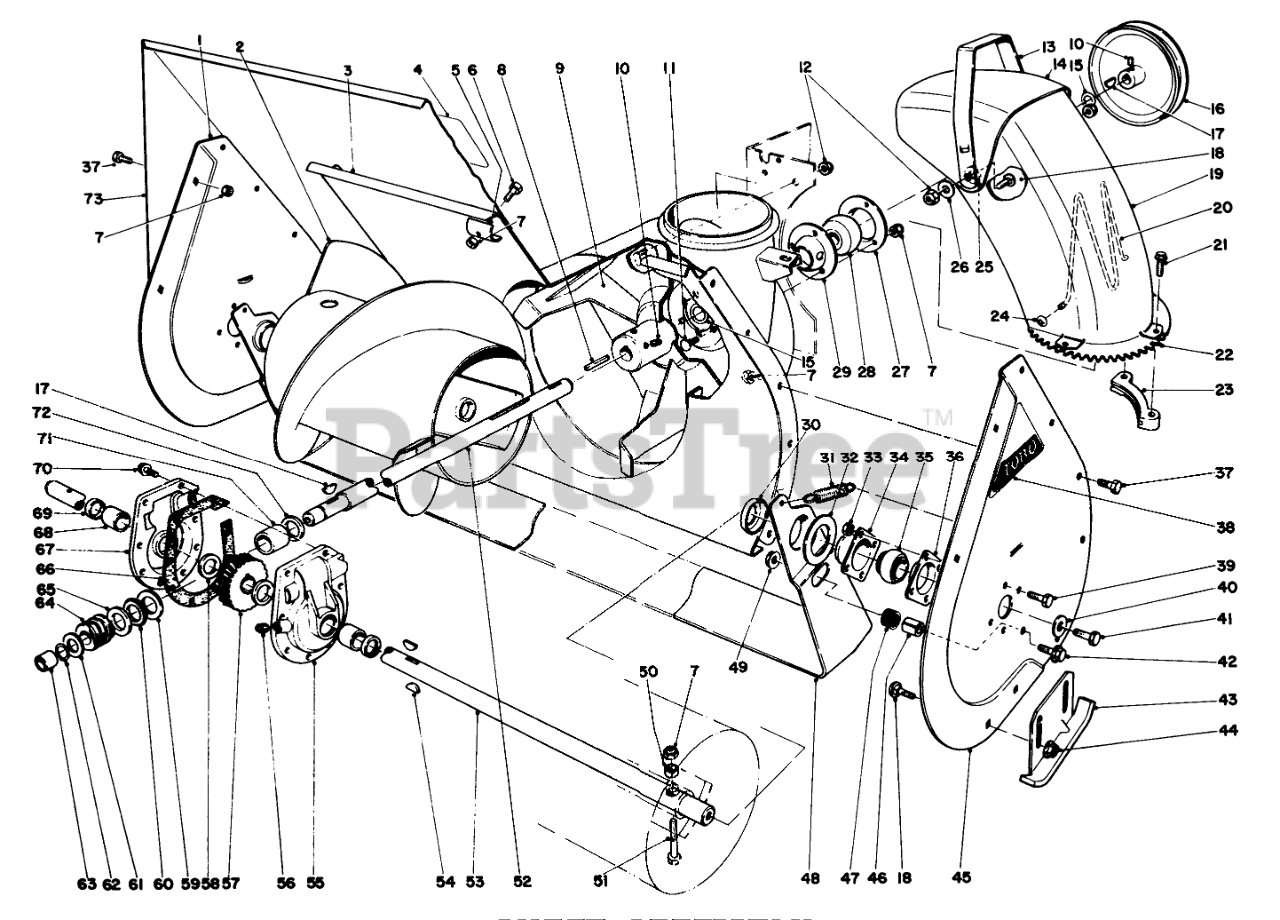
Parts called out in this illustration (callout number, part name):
1	RH AUGER SIDE PLT R
2	Auger Right
3	AUGER HSG WA RO
4	Decal
5	SHIELD CLAMP R
6	SCREW-HH
7	NUT-LOCK, NI
9	IMPELLER WA RO
10	SCREW-SET, SQH
11	BOLT-CARR
12	NUT-LOCK, CONE
13	DEFLECTOR HANDLE B
14	Chute Deflector
15	WASHER
16	IMPELLER PULLEY
17	KEY-WOODRUFF
18	SCREW-CARR
19	Chute
20	WIRE-CHUTE
21	SPECIAL SCREW
22	Chute Swivel Gear
23	CHUTE RETAINER
24	NUT-PUSH
25	WASHER-RUBBER
26	WASHER-BELLEVILLE
27	FLANGE-CUP, BEARING
28	Ball Bearing
29	FLANGE-CUP, BEARING
30	Positioner-Scraper
31	SPRING-TENSION
32	SCRAPER BLADE SPACER
33	NUT-LOCK, CONE
34	BEARING-FLANGE, FRONT
35	BEARING
36	BEARING-FLANGE, REAR
37	SCREW-HH
38	AUGER SIDE PLT DECAL
39	SCREW-HH
40	WASHER
41	SCREW-HH
42	SCREW-HHF
43	AUGER SKID WA R
44	NUT-HHF, WHIZ
45	LH AUGER SIDE PLT R
46	SCRAPER STOP SPACER
47	SCRAPER STOP CUSHION
48	24 SCRAPER BLD
49	NUT-HF
50	SPACER-HUB, AUGER
51	Auger Bolt
52	Shaft Impeller
53	24 AUGER SHAFT
54	KEY-WOODRUFF
55	Gear Case (Incl. Ref. #68 & 69)
56	PLUG-PIPE, SQH
57	GEAR-WORM, 27T
58	WASHER-THRUST
59	WASHER-THRUST
60	BEARING-THRUST
61	WASHER-THRUST
62	Ring-Snap
63	BUSHING
65	THRUST-WASHER
66	asket
67	Gear Case (Incl. Ref. #68 & 69)
68	BUSHING
69	SEAL-OIL
70	SCREW-TAPTITE
71	BUSHING-SPECIAL
72	RING-QUAD
73	AUGER EXT 24 SCND R
